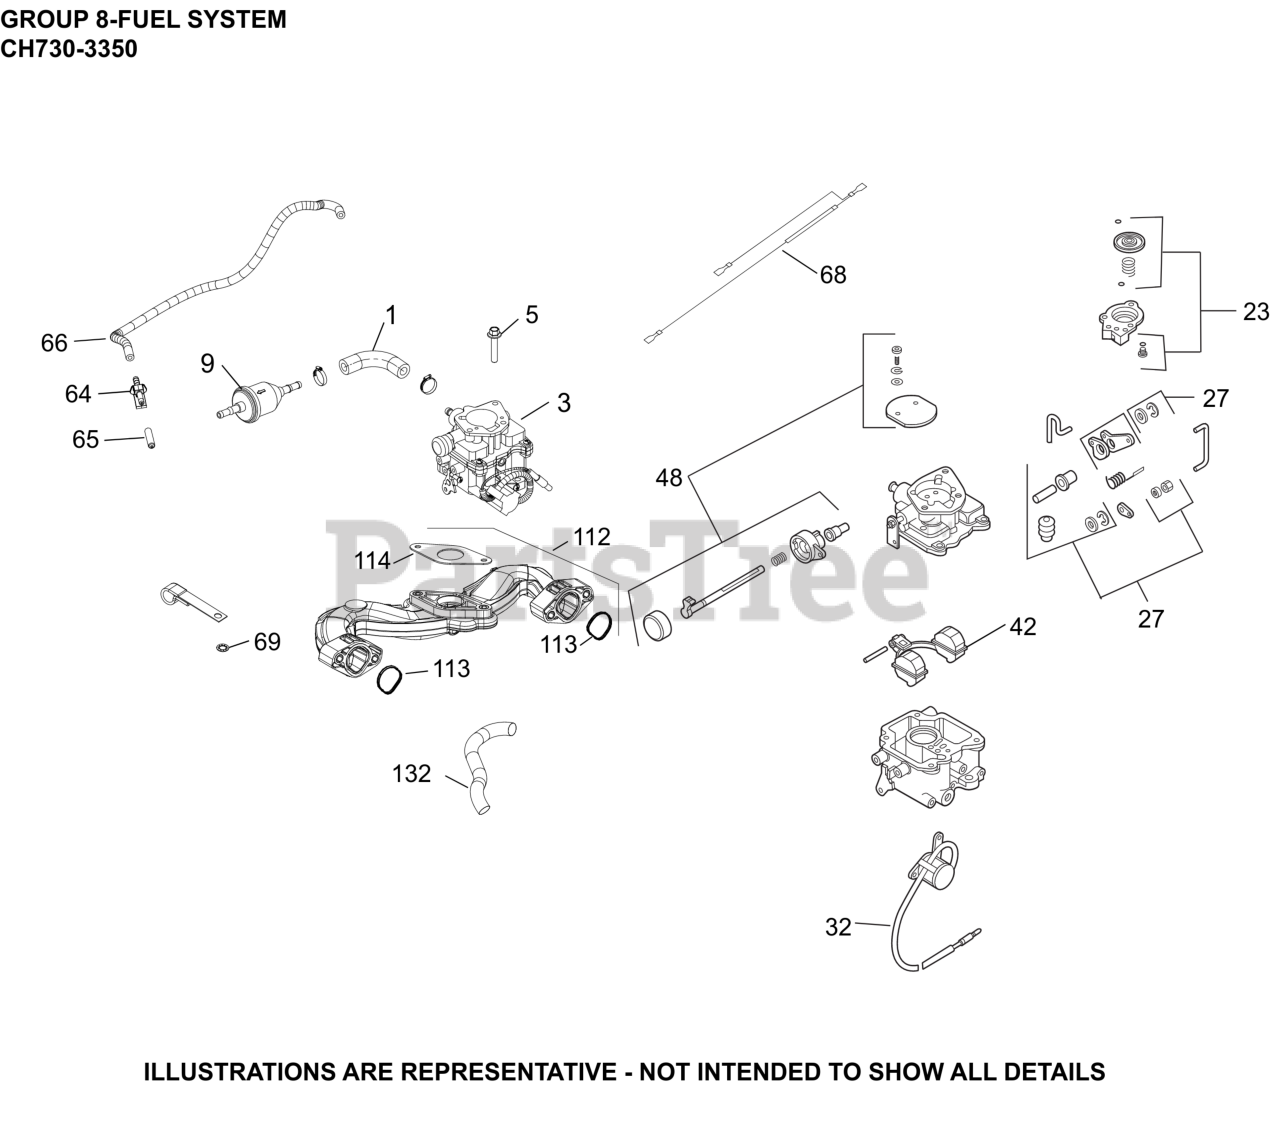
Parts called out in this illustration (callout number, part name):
1	HOSE,LW PERM.FUEL 24.00"-USE 25 111 81-S
3	KIT, CARBURETOR COMPLETE
5	SCREW, FLG M6X1.0X25
9	FILTER, FUEL
23	KIT, REPAIR ACC PUMP
27	KIT, REPAIR-ACC PUMP SEAL
32	KIT, SOLENOID
42	KIT, REPAIR FLOAT
48	KIT, REPAIR CHOKE
64	CONNECTOR, EVAPORATIVE
65	CAP, MASKING
66	HOSE, EVAPORATIVE 20"- (#24326143S)
68	LEAD, GROUND
69	WASHER, INT TOOTH LOCK 1/4"
112	INTAKE MANIFOLD W/GASKETS
113	O-RING, INTAKE PORT
114	GASKET, CARBURETOR (PIM, CH)
132	SLEEVE, ANTI ABRASION-USE 25 431 12-S
NI	KIT, HIGH ALT (8,000+ FT)
NI	KIT, HIGH ALT (4000-8000 FT)
NI	KIT, REPAIR CARBURETOR
